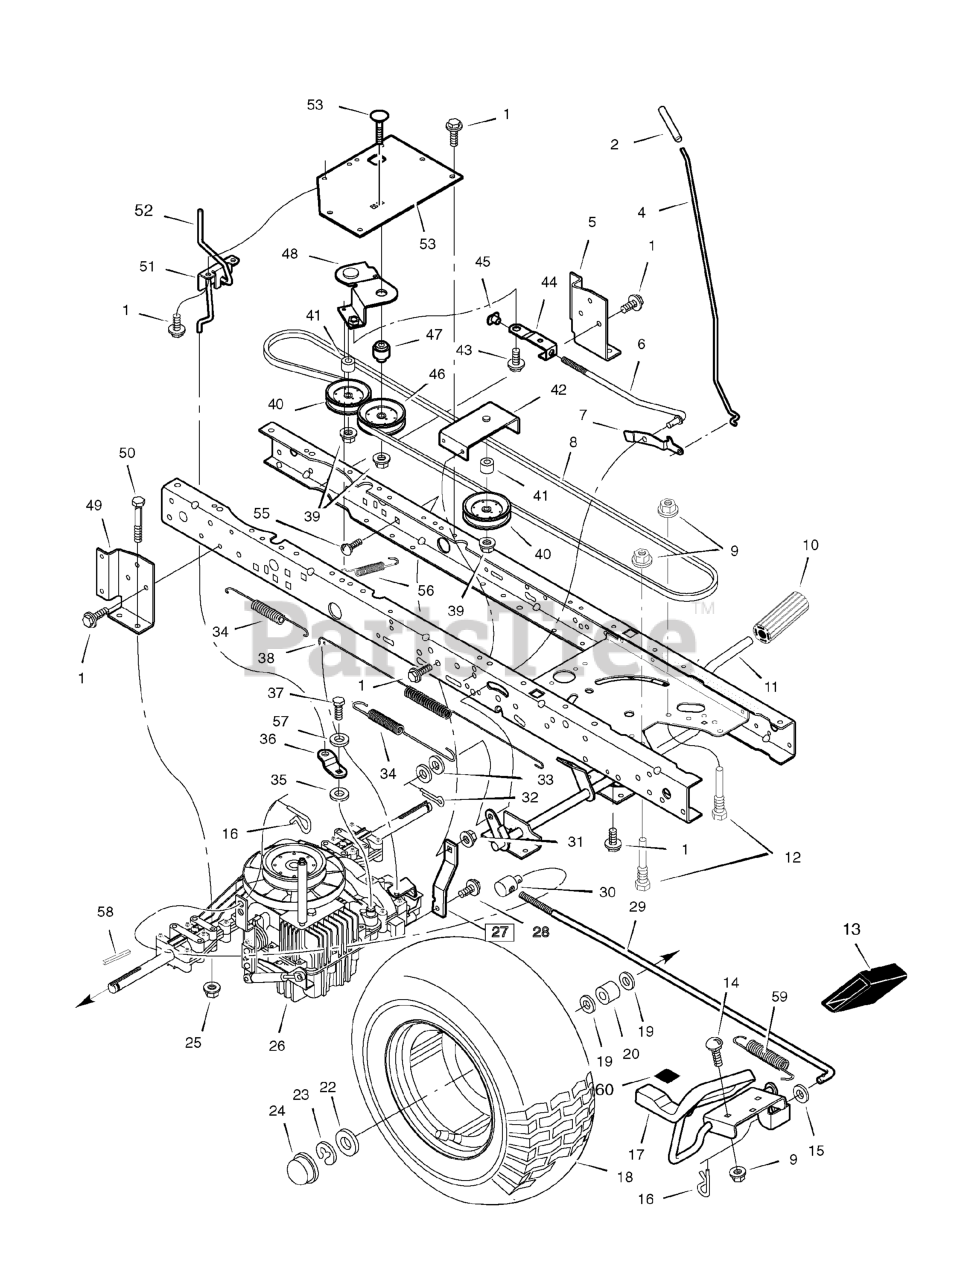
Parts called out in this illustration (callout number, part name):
2	Grip, Parking Brake
4	Rod, Parking Brake
5	Bracket, Transaxle Left
6	Rod, Clutch
7	Latch, Parking Brake
8	V-Belt, Drive
9	Nut, Flange
10	Pedal, Brake/Clutch
11	Assembly, Brake Pedal
12	Screw, Guide
13	Pad, Pedal Black
14	Bolt, Carriage
16	Pin, Hair
17	Pedal Assembly, Hydro
18	Wheel & Tire Assembly Rear 20"
24	Cap, Hub
25	Nut, Centerlock
26	Transaxle **
27	Strap, Torque
29	Rod, Control
30	Nut, Adjusting
31	Nut, Centerlock
32	Pin, Cotter
34	Spring, Extension
36	Arm, Disconnect
37	Capscrew
38	Spring, Brake
39	Locknut, Flange
40	Pulley, Idler
42	Bracket, Idler Assembly
43	Bolt, Shoulder
44	Link, Clutch
45	Nut, Tee
46	Pulley, Idler
47	Bushing, Pivot
48	Arm Assembly, Idler
49	Bracket, Transaxle -Right
50	Bolt, Hex
51	Bracket, Disconnect
52	Rod, Disconnect
53	Bracket, Idler Pivot
54	Bolt, Carriage
55	Bolt, Carriage
56	Spring, Clutch
58	Key, Square
60	Pad, Toe Reverse
